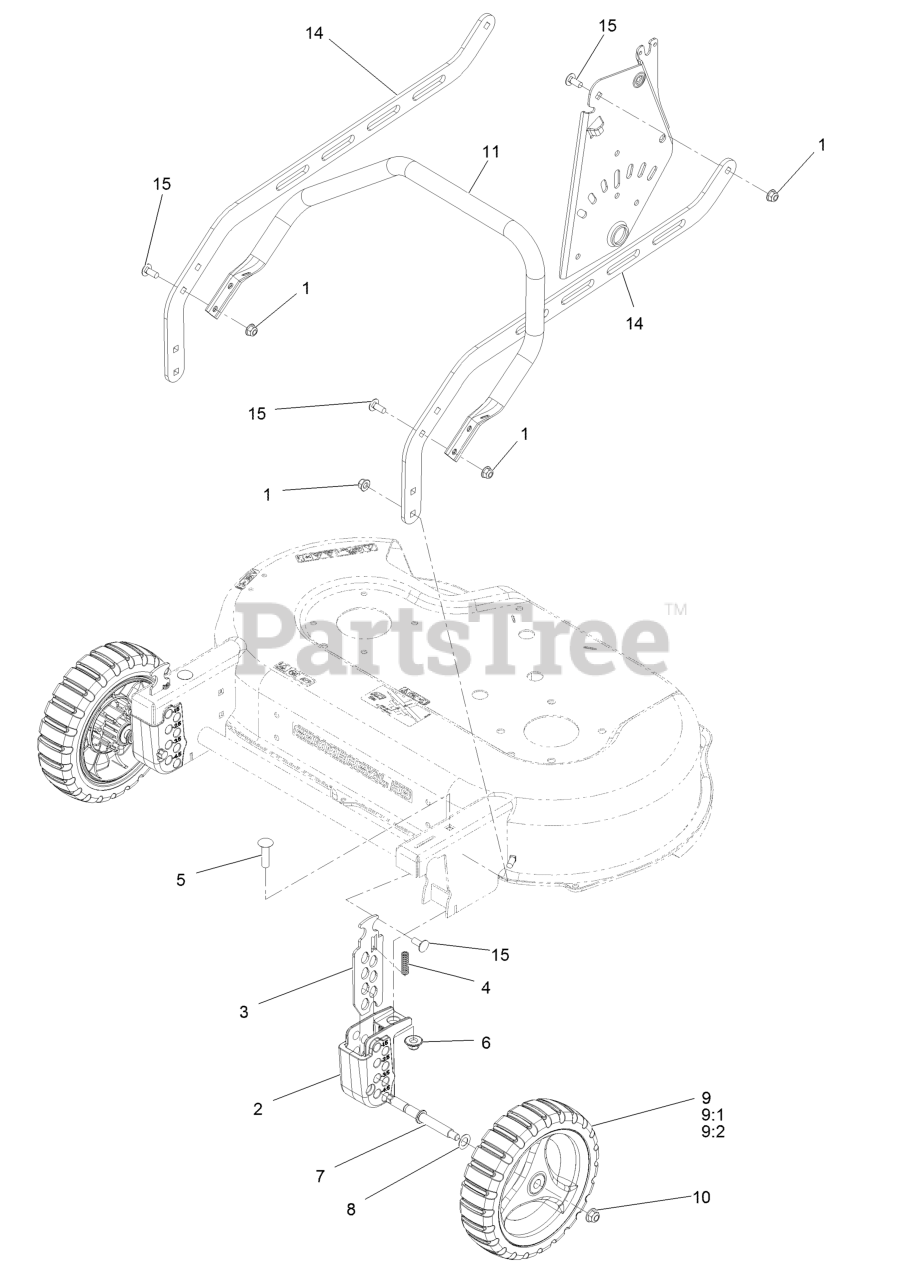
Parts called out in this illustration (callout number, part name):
1	NUT-HF, NI
2	BLOCK-FRONT QUADRANT
3	PLATE, FRONT HEIGHT
4	SPRING-COMPRESSION
5	SCREW-CARR
6	Nut-Nyloc 3/8-16 Flg
7	AXLE-WHEEL
8	WASHER-PLAIN
9	WHEEL ASM, 9" W/BEARINGS
9:1	WHEEL ASM, 9"
9:2	BEARING-BALL
10	NUT-HF, NI
11	GUARD-ENGINE
15	SCREW-CARR
